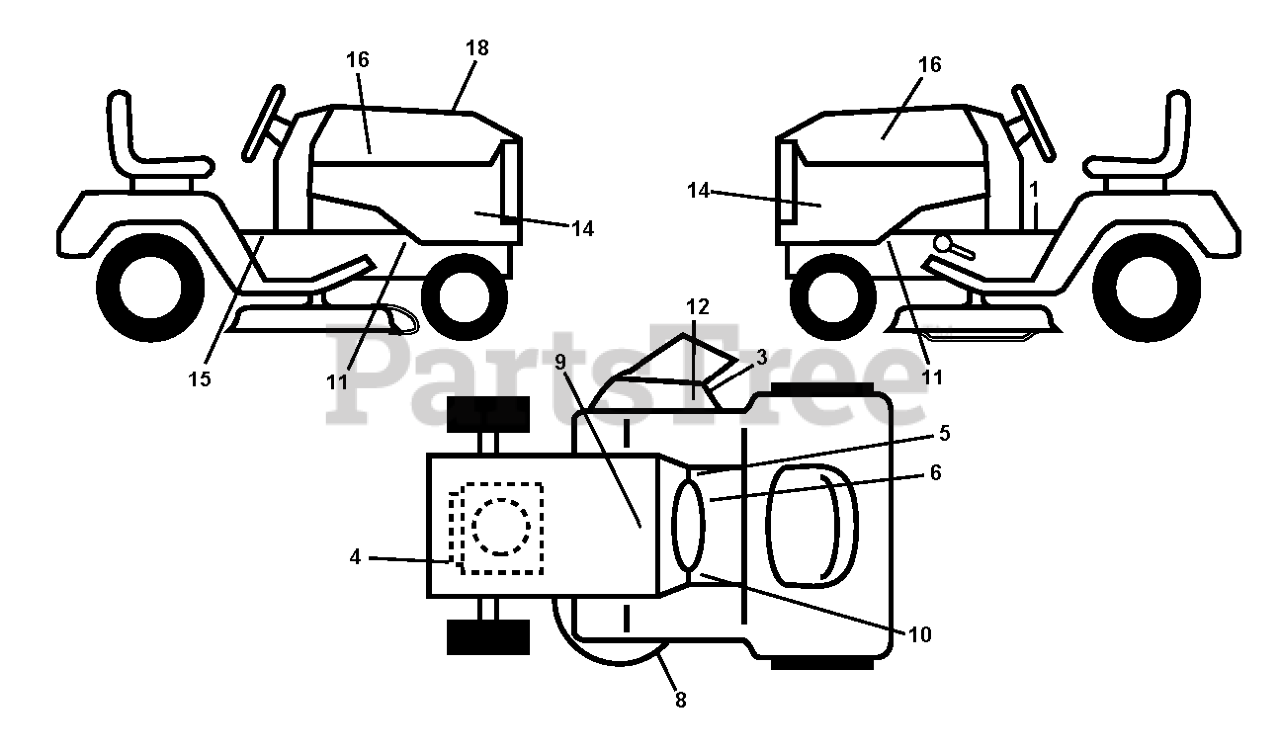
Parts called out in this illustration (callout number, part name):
1	LABEL
3	DECAL, DEFLECT WARNING
4	DECAL
5	DECAL PARK BRAKE
6	DECAL
8	DECAL.MOWER.SCH.48/54
9	DECAL BTRY SYMBOLS
10	DECAL
12	DECAL.INTERNATIONL.CUTFINGER
14	DECAL PNL SD.
15	DECAL.FENDER
16	DECAL.HOOD.LOGO.ORANGE.HUSQVAR
18	DECAL RPL KO
